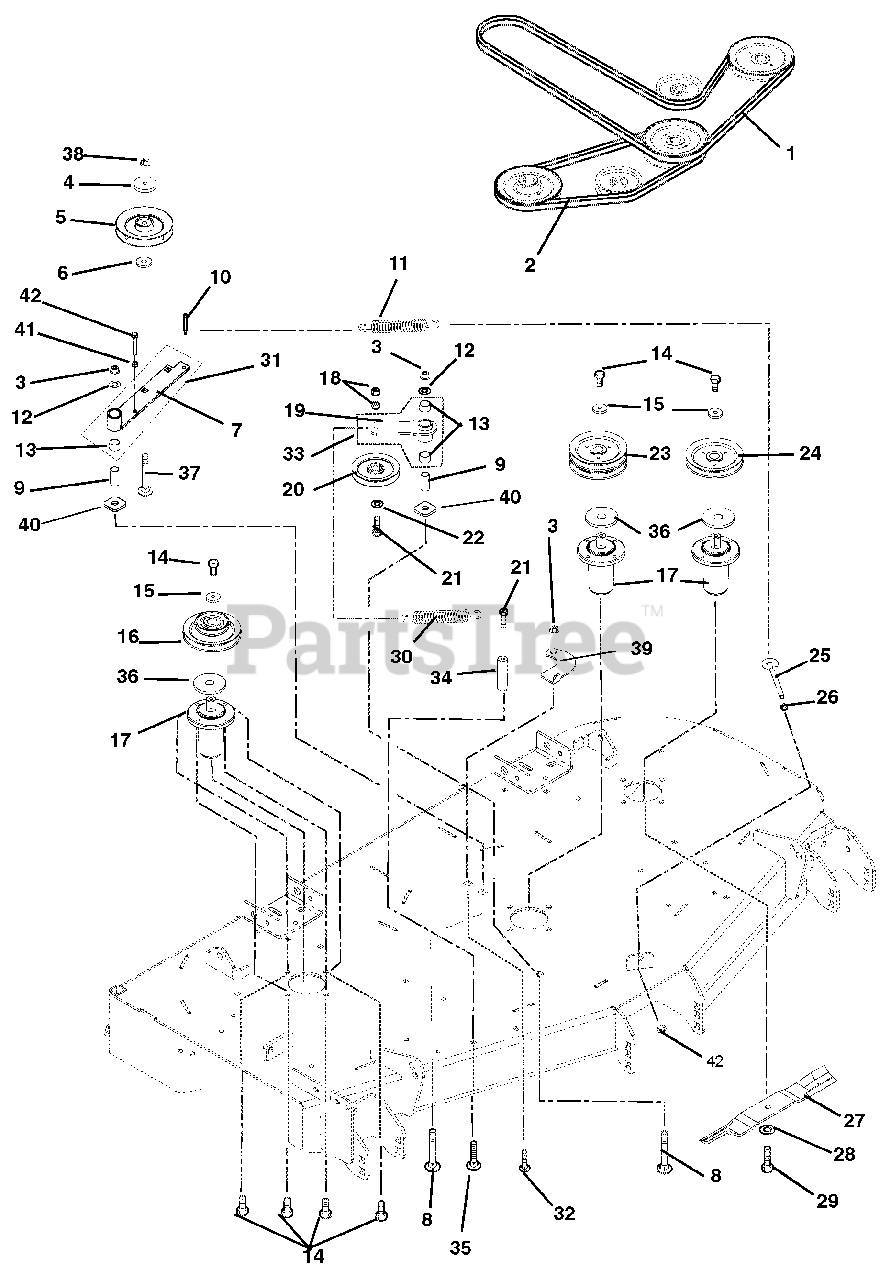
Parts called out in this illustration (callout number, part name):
1	Belt, BB-Wrapped Clutching Hex
2	V-Belt, 63" Long Cog B-Section
3	Nut, .50-13 Nyloc Flange
4	Cap, Idler Bearing Sealing
5	Sheave .50" ID x 6.00" OD V-Idler
6	Bushing, Spacer .502 x .997 x 0.50
7	Arm, Idler
8	Bolt, Round Head Square Neck .50-13 x 3.50 Grade 5
9	Bushing, Spacer .502 x .997 x 2.03
10	Bolt, Shoulder .38-16 x .30 Hex
11	Spring, Extension
12	Washer, Flat Steel .563 x 1.38 x .109
13	Bushing, 1.00 x 1.125 x 1.936
14	Bolt, Hex .38-16 x 1.00 (Torque = 380-480 lbf-in (42.93-54.23 N•m))
15	Washer, Flat Steel .406 x 1.50 x .245
16	Pulley, Double- 1" ID x 6.75" & 4.25" OD
17	Assembly, Spindle - Long G3500
18	Nut, Locking-Center .38-16
19	Weldment, Idler Arm
20	Sheave, .38" ID x 5.00"OD V-Idler
21	Bolt, Hex .38-16 x 2.25
22	Washer, Flat Steel .406 x .812 x .065
23	Pulley, Double-1" ID x 6.75" OD
24	Pulley, V 1" ID x 6.75" OD
25	Bolt, .38-16 x 4.50 .62 Diameter Eye
26	Nut, Hex, Jam .375-16
27	Blade, Mower (20.50")
28	Washer, Bellville .63 x 1.625 x .14
29	Bolt, Hex .62-18 x 1.75 Grade 8 (Torque = 115-160 lbf-in (12.99-18.08 N•m))
30	Spring, Extension
31	Assembly, PTO Idler Pivot Arm (Includes item # 7 and item # 13)
32	Bolt, Round Head Square Neck .50-13 x 1.5, Full Thread, Grade 5
33	Assembly, Idler Pivot Arm (Includes item # 13 and item # 19)
34	Nut, Coupling .375-16 x 1.75
35	Bolt, Round Head Square Neck .38-16 x 1.00
36	Retainer, Grease
37	Bolt, Round Head Square Neck .50-13 x 3.00 Grade 5
38	Nut, Locking Center .50-13
39	Stop, PM320 PTO Idler Arm
40	Washer, Flat Steel .640 x 1.75 x .250
41	Nut, Hex .38-16
42	Bolt, Hex .38-16 x 2.75
